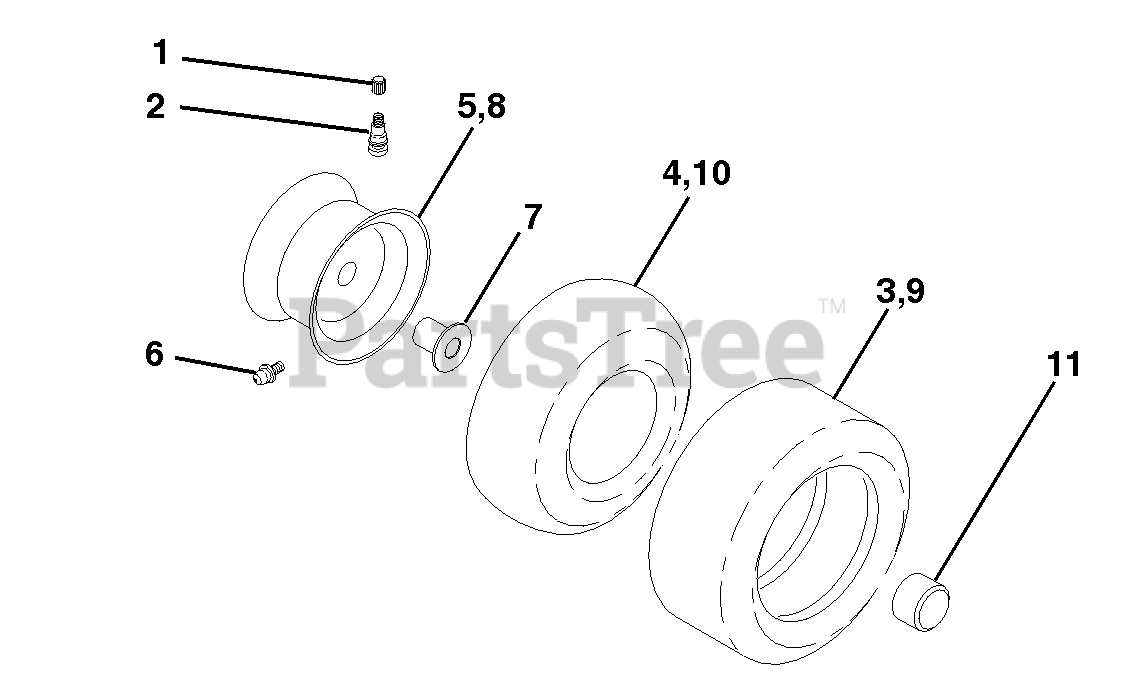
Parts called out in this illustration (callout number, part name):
1	Cap Valve Tire
2	Stem Valve
3	Tire F Ts 15 X 6 0 - 6 Service
4	Tube Front
5	Rim Asm 6" front Silver Service
6	Fitting Grease
7	Bearing Flange
8	Rim Asm 8" rear Silver Service
9	Tire R Ts 20 x 10-8 C Service
10	Tube Rear
11	Cap Axle Blk 1 50 X 1 00
